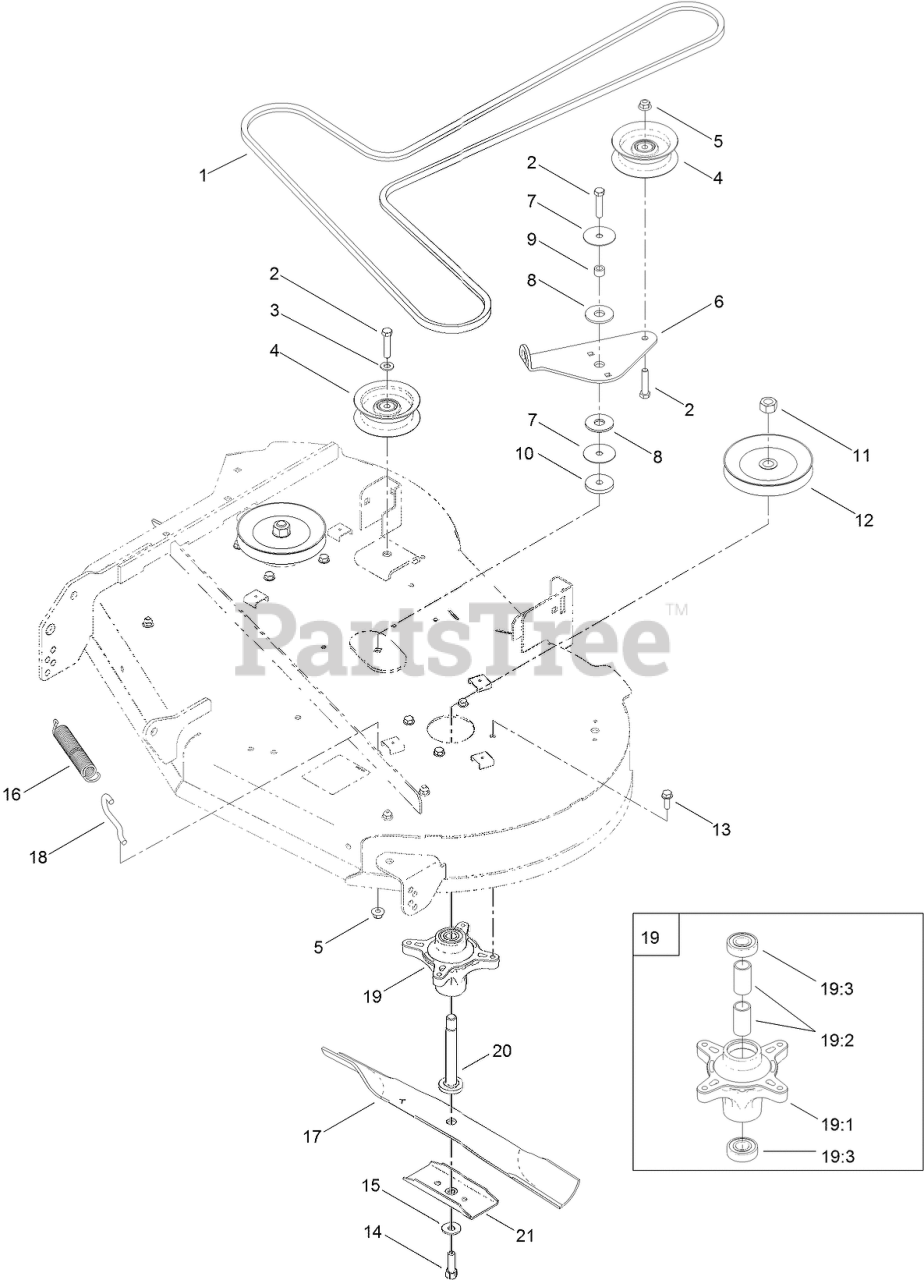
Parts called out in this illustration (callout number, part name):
1	V-BELT
2	SCREW-HH
3	WASHER-FLAT
4	PULLEY-IDLER, FLAT
5	NUT-HF, NI
6	ARM-IDLER
7	WASHER
8	WASHER-FRICTION, COMPOSITE
9	SPACER
10	SCREW-HH
11	NUT-HEX
12	Pulley
13	SCREW-TAPTITE
14	SCREW-HH
15	WASHER-BELLEVILLE
16	SPRING-EXTENSION
17	BLADE-21.6 INCH
18	HOOK-RETURN, SPRING
19	SPINDLE ASM
19:1	SPINDLE
19:2	SPACER
19:3	BEARING-BALL
20	SHAFT-SPINDLE
21	STIFFENER-BLADE
